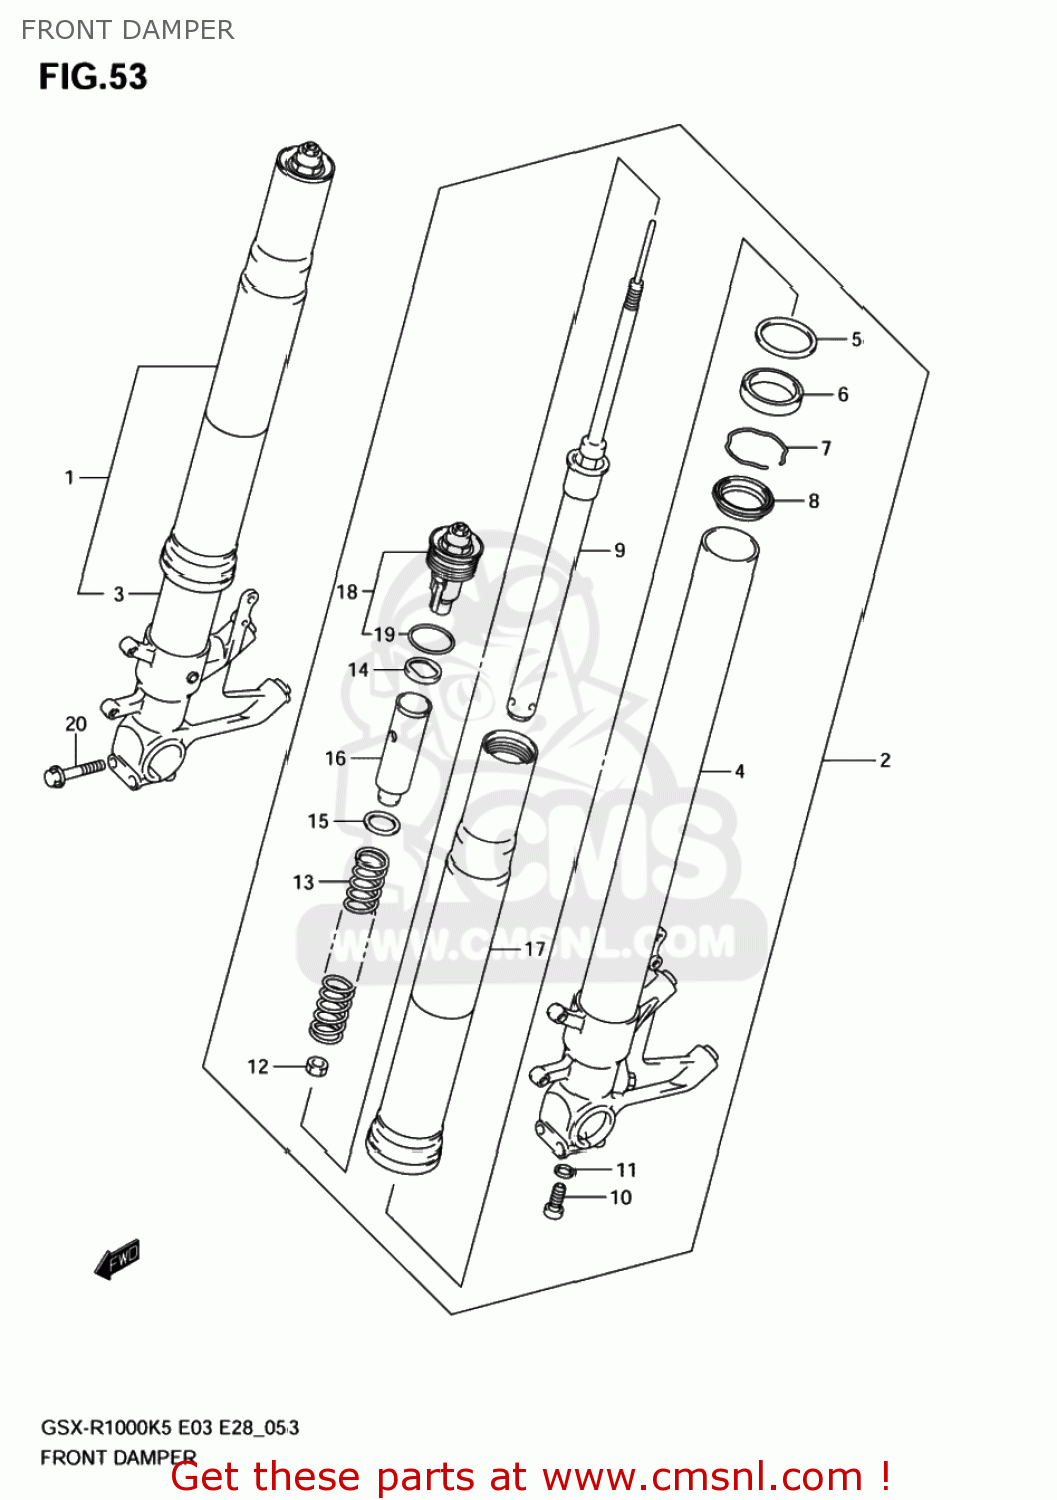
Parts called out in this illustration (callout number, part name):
1	DAMPER ASSY,FR FORK,R
2	DAMPER ASSY,FR FORK,L
3	TUBE,INNER,R
4	TUBE,INNER,L
5	WASHER
6	SEAL,OIL
7	RING,STOPPER
8	SEAL,DUST
9	CYLINDER
10	BOLT
11	GASKET (NAS)
12	NUT
13	SPRING,FR
14	GUIDE,SPRING
15	WASHER
16	SPACER,SPRING
17	TUBE,OUTER
18	CAP,FR FORK
19	O RING
20	BOLT
